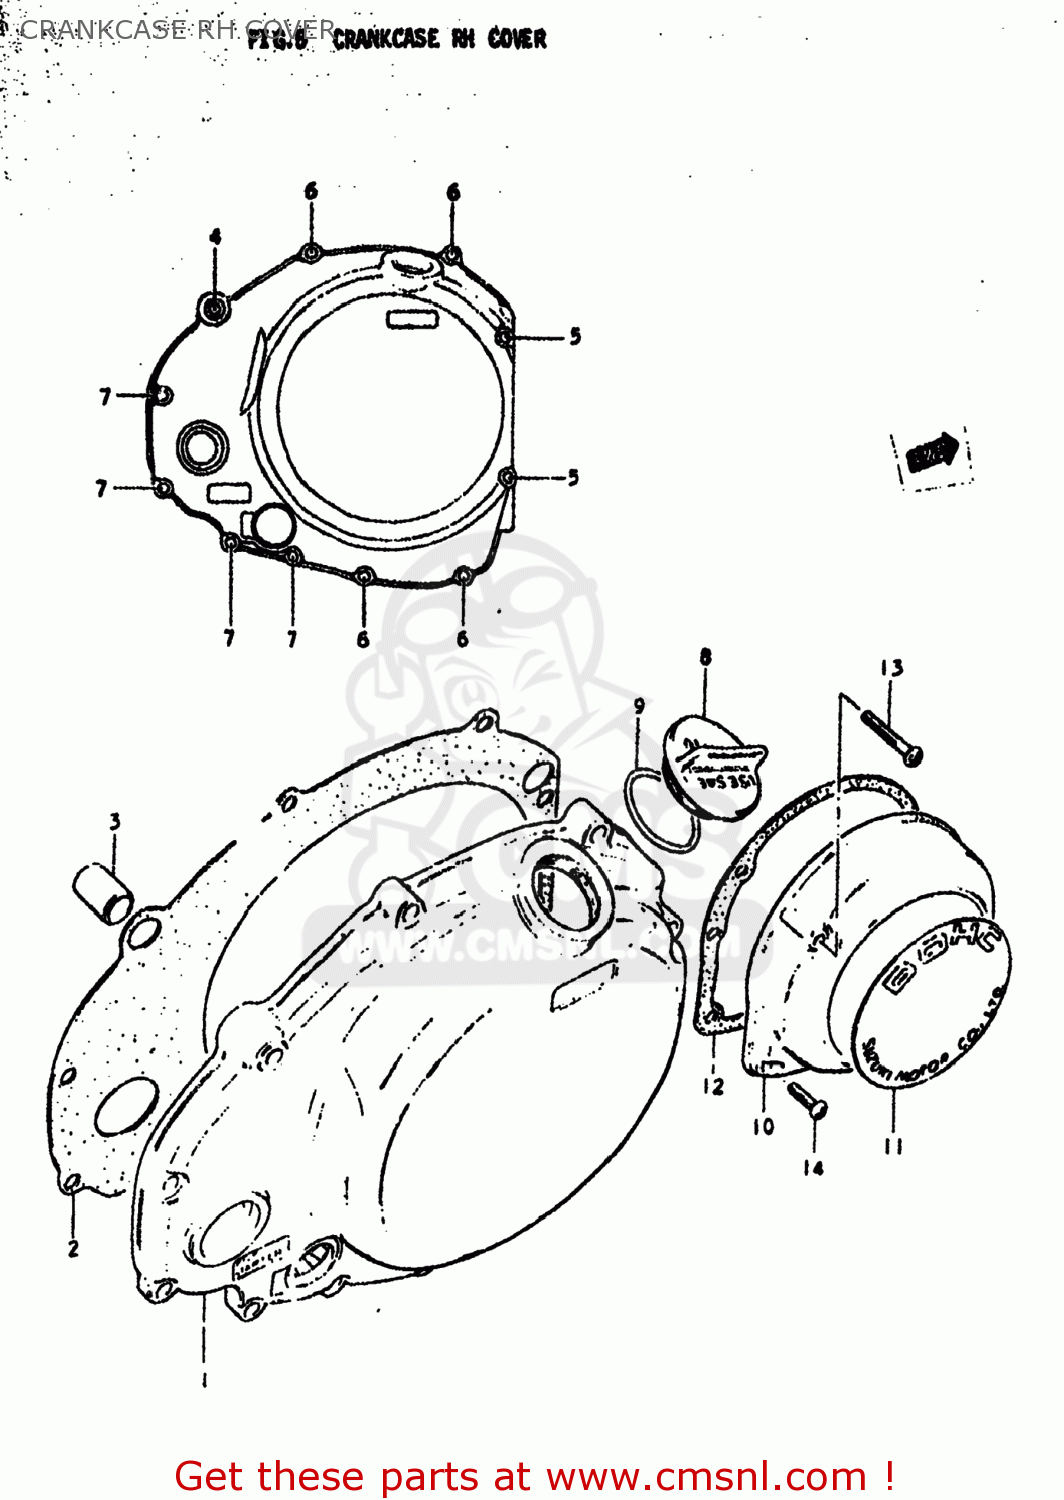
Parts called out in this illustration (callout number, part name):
1	COVER,CLUTCH
2	GASKET,CLUTCH COVER (MCA)
3	PIN
4	SCREW (6X45)
5	SCREW
6	SCREW
7	SCREW
8	CAP
9	O RING(D:2.2,ID:32)
10	COVER,CONTACT BREAKER
11	EMBLEM
12	GASKET,CONTACT BREAKER COVER (NAS)
13	SCREW
14	SCREW
